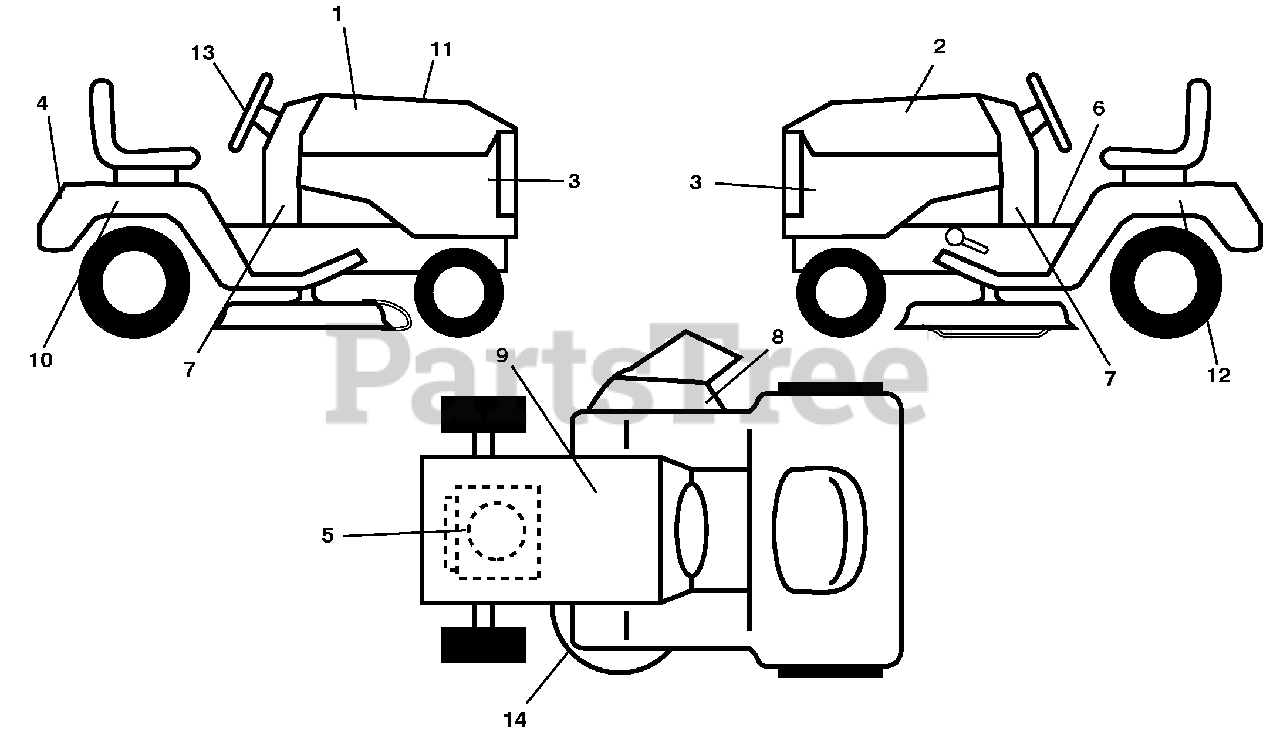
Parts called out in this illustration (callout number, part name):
1	Decal, Hood RH
2	Decal, Hood LH
3	Decal, Side Panel
4	Decal, Fender
5	Decal, Engine
6	Decal, Fender Operator's
7	Decal, Lower Dash
8	Decal, Warning
9	Decal, Battery Dnge/Poi
10	Decal, Fender RH
11	Decal, Replacement
12	Decal, Fender LH
13	Decal, Steering Wheel
14	Decal, Mower Schematic
14	Pad, Pedal
14	Decal, Bypass
14	Pad, Footrest, LH
14	Manual, Operator's (Eng/French)
14	Manual, Parts
